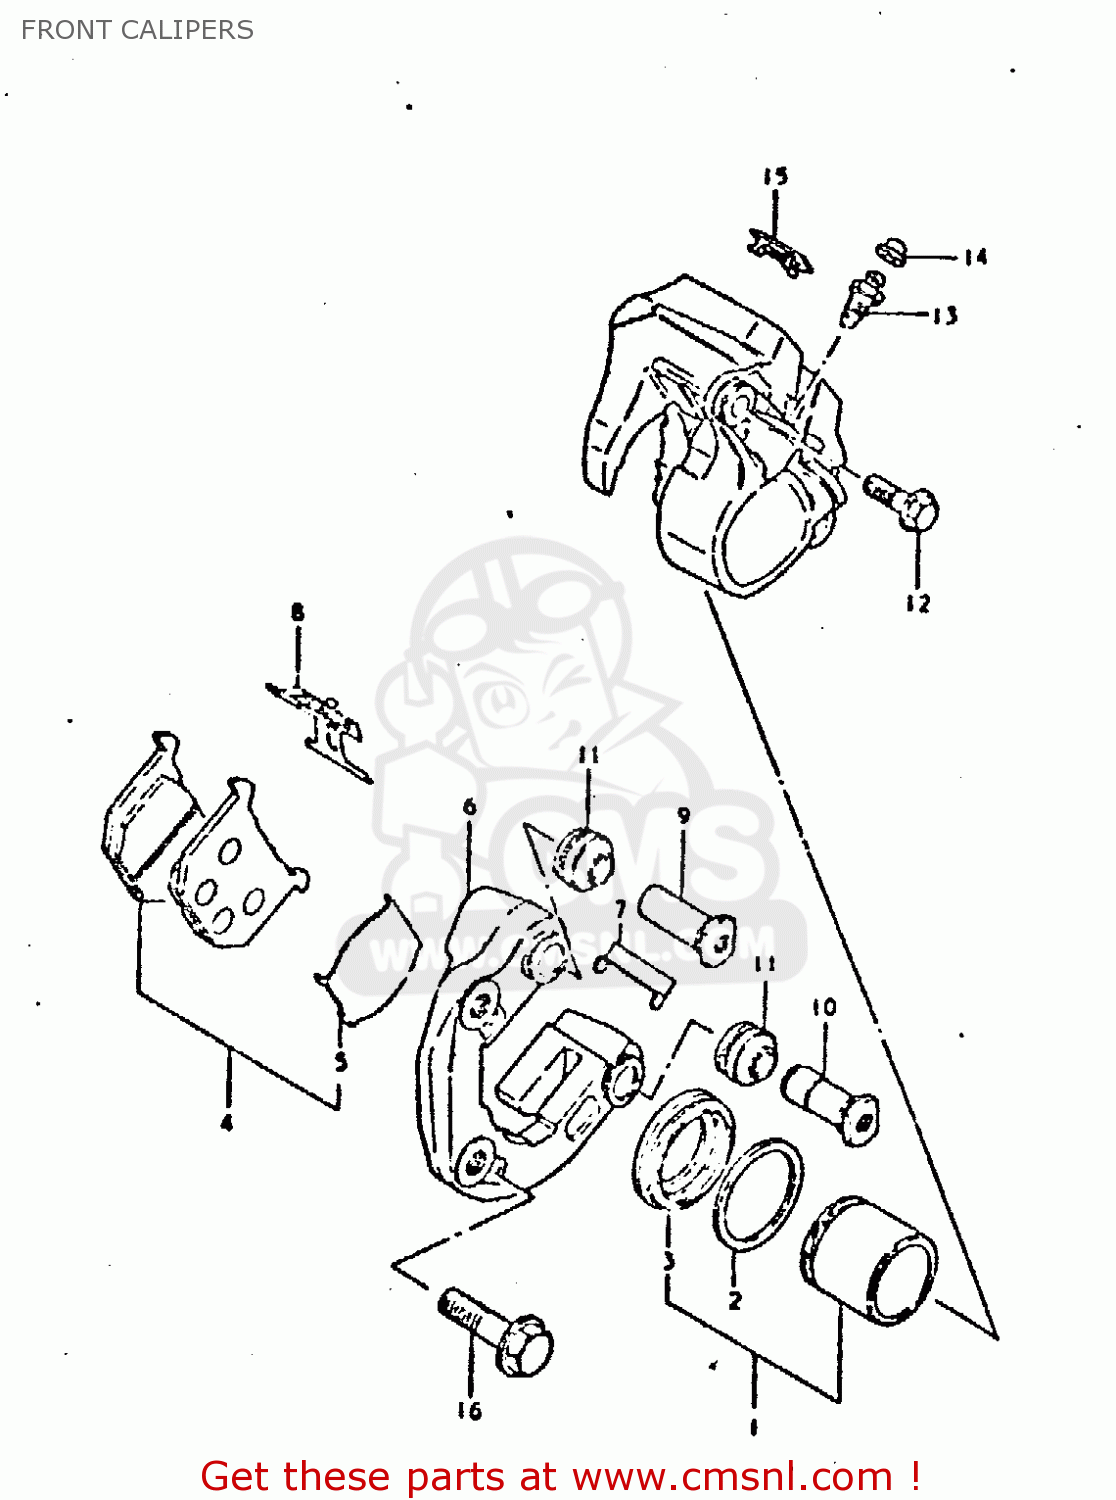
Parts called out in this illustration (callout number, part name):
1	PISTON SET
2	SEAL,PISTON
3	BOOT,PISTON
4	PAD SET (MCA)
5	SHIM,PAD
6	CARRIER,CALIPER,LEFT
7	GUIDE,PAD
8	SPRING,PAD
9	AXLE NO.1
10	AXLE NO.2
11	BOOT,AXLE
12	BOLT,CALIPER HOUSING
13	BLEEDER
14	CAP,BREATHER
15	COVER,INDICATOR
16	BOLT
